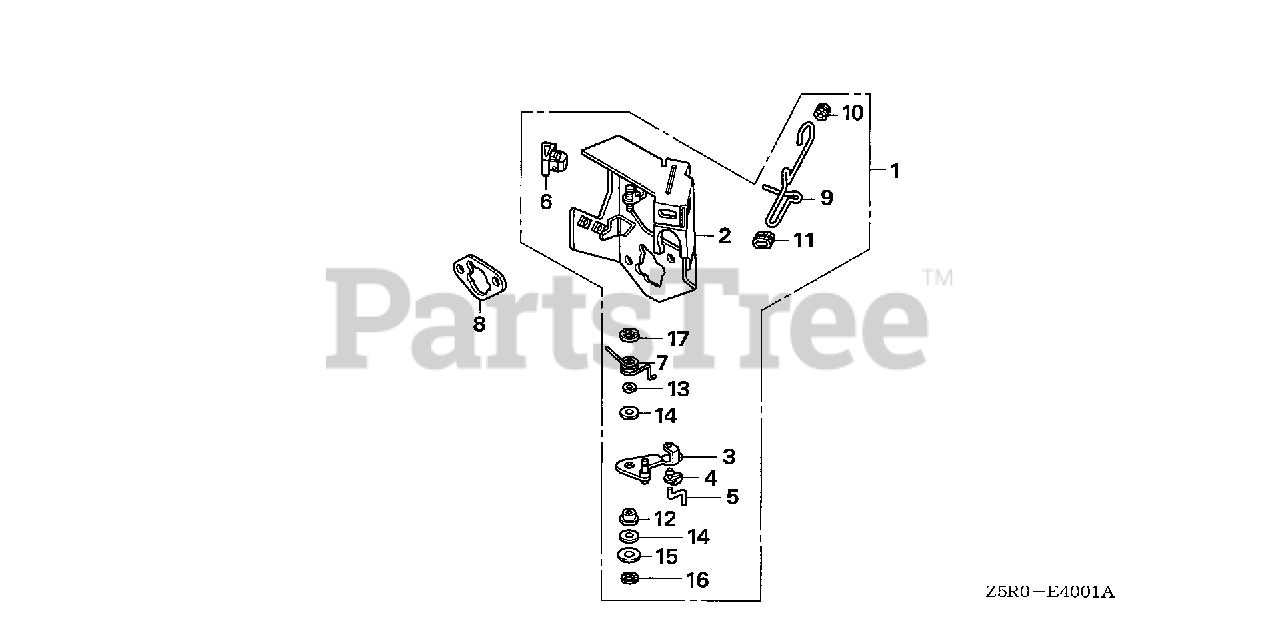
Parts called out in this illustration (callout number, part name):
1	STAY ASSY., MANUAL CHOKE
2	STAY, SOLENOID
3	LEVER, CHOKE
4	JOINT, ROD
5	ROD, CHOKE
6	STOPPER, CHOKE ROD
7	SPRING, MANUAL CHOKE
8	GASKET, AIR CLEANER
9	ROD, CHOKE CONTROL
10	GROMMET, CHOKE ROD
11	GUIDE, CHOKE ROD
12	BUSH, ARM PIVOT
13	WASHER, CHOKE LEVER
14	SEAL, CHOKE LEVER
15	WASHER, PLAIN (5MM)
16	E-RING (4MM)
17	E-RING (7MM)
